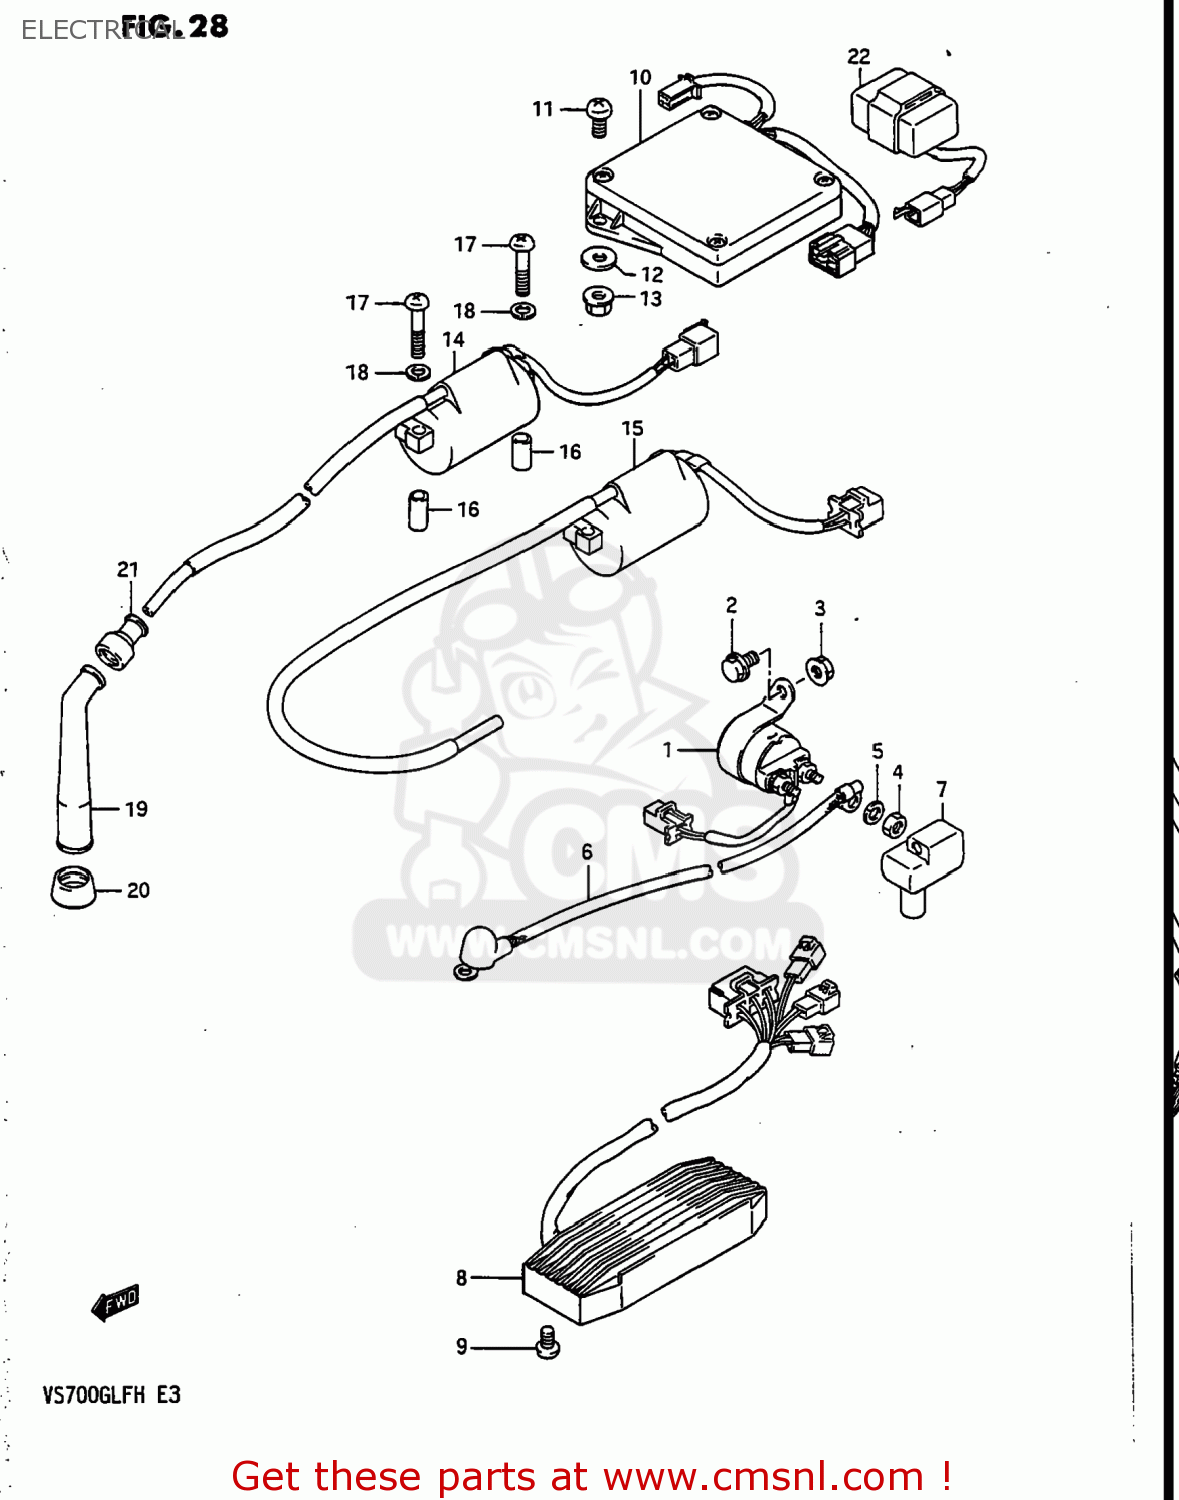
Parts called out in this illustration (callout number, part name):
1	RELAY ASSEMBLY,STARTING MOTOR
2	BOLT
3	NUT
4	NUT
5	WASHER,LOCK
6	WIRE,STARTER MOTOR LEAD
7	CAP,STARTER RELAY
8	RECTIFIER ASSY
9	BOLT
10	IGNITOR UNIT
11	SCREW
12	WASHER(6.5X20X2)
13	NUT
14	COIL ASSEMBLY,IGNITION
15	COIL ASSEMBLY,IGNITION
16	SPACER(6.4X10X19)
17	SCREW (5X38)
18	LOCK WASHER
19	CAP,SPARK PLUG
20	SEAL,SPARK PLUG CAP
21	SEAL,SPARK PLU
22	RELAY ASSY,FUEL CUT
